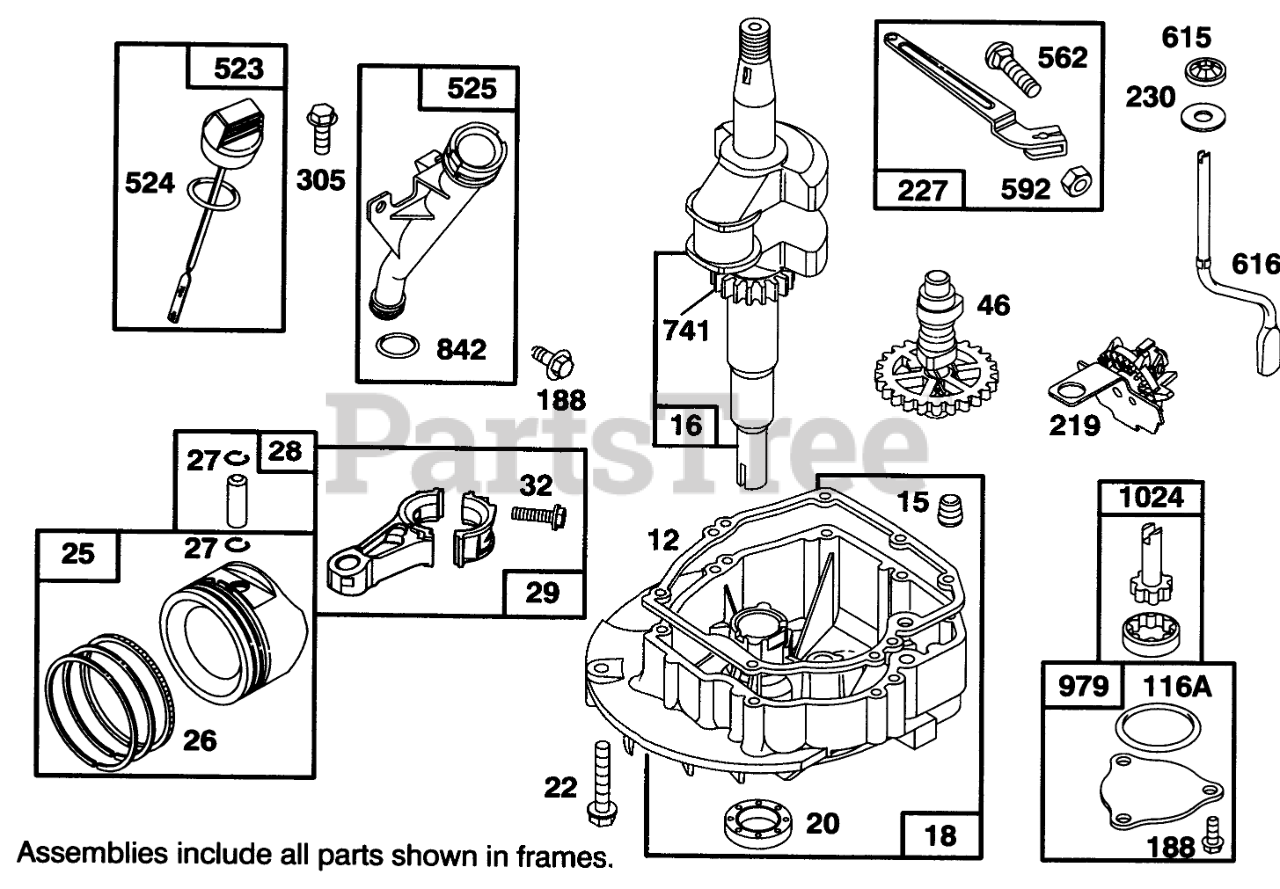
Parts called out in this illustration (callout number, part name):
12	ENGINE BASE GASKET
15	PIPE PLUG
16	Crankshaft
18	ENGINE SUMP
20	SEAL-OIL
22	SCREW - ENGINE BASE
25	STD PISTON ASSEMBLY
26	STD RING SET
27	PISTON PIN LOCK
28	PIN ASM - PISTON
29	CONNECTING ROD
32	SCREW - CONNECTING ROD
46	CAM GEAR
116A	O RING SEAL
188	Screw-Cap
219	GOVERNOR/OIL SLINGER
227	GOVERNOR LEVER ASSEMBLY
230	WASHER
305	SCREW - HEX HEAD
523	DIPSTICK-OIL
524	O-RING
525	OIL FILLER TUBE
562	GOVERNOR LEVER BOLT
592	HEX NUT
615	FASTENER
616	GOVERNOR CRANK
741	TIMING GEAR
842	O-RING
979	OIL PUMP COVER
1024	OIL PUMP
